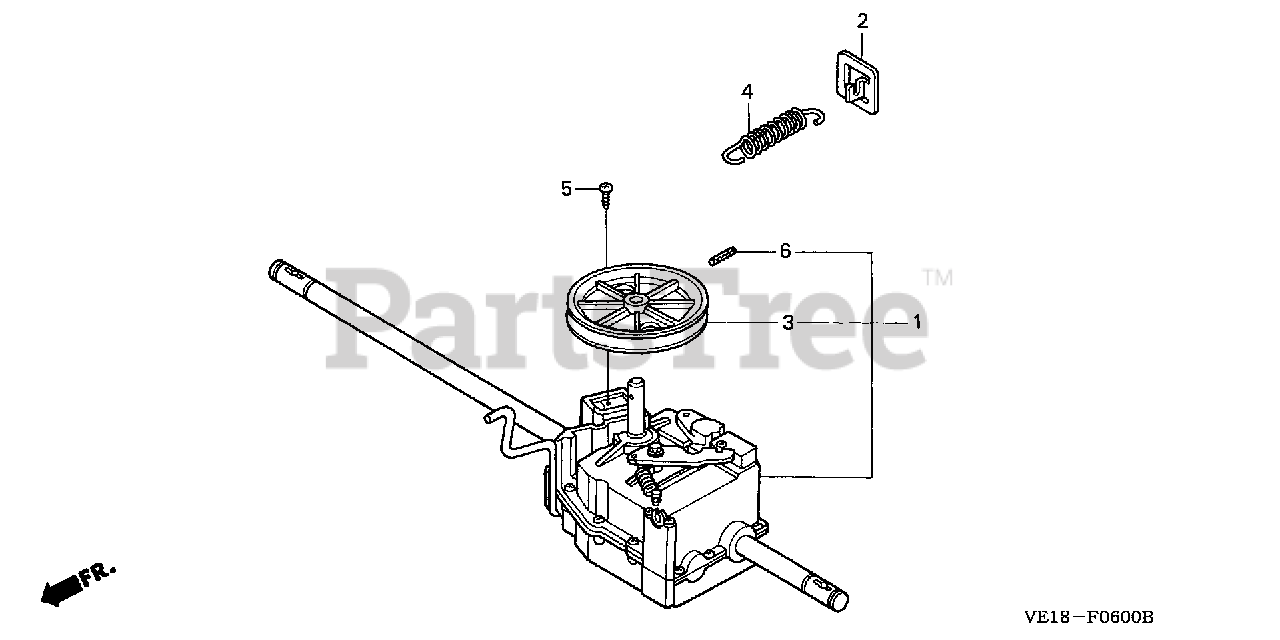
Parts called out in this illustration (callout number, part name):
1	TRANSMISSION ASSY.
2	PLATE, TENSION SPRING
3	PULLEY, DRIVEN
4	SPRING, WHEEL TENSION
5	SCREW, TAPPING (5X12) (PO)
6	PIN, SPRING (5X36)
